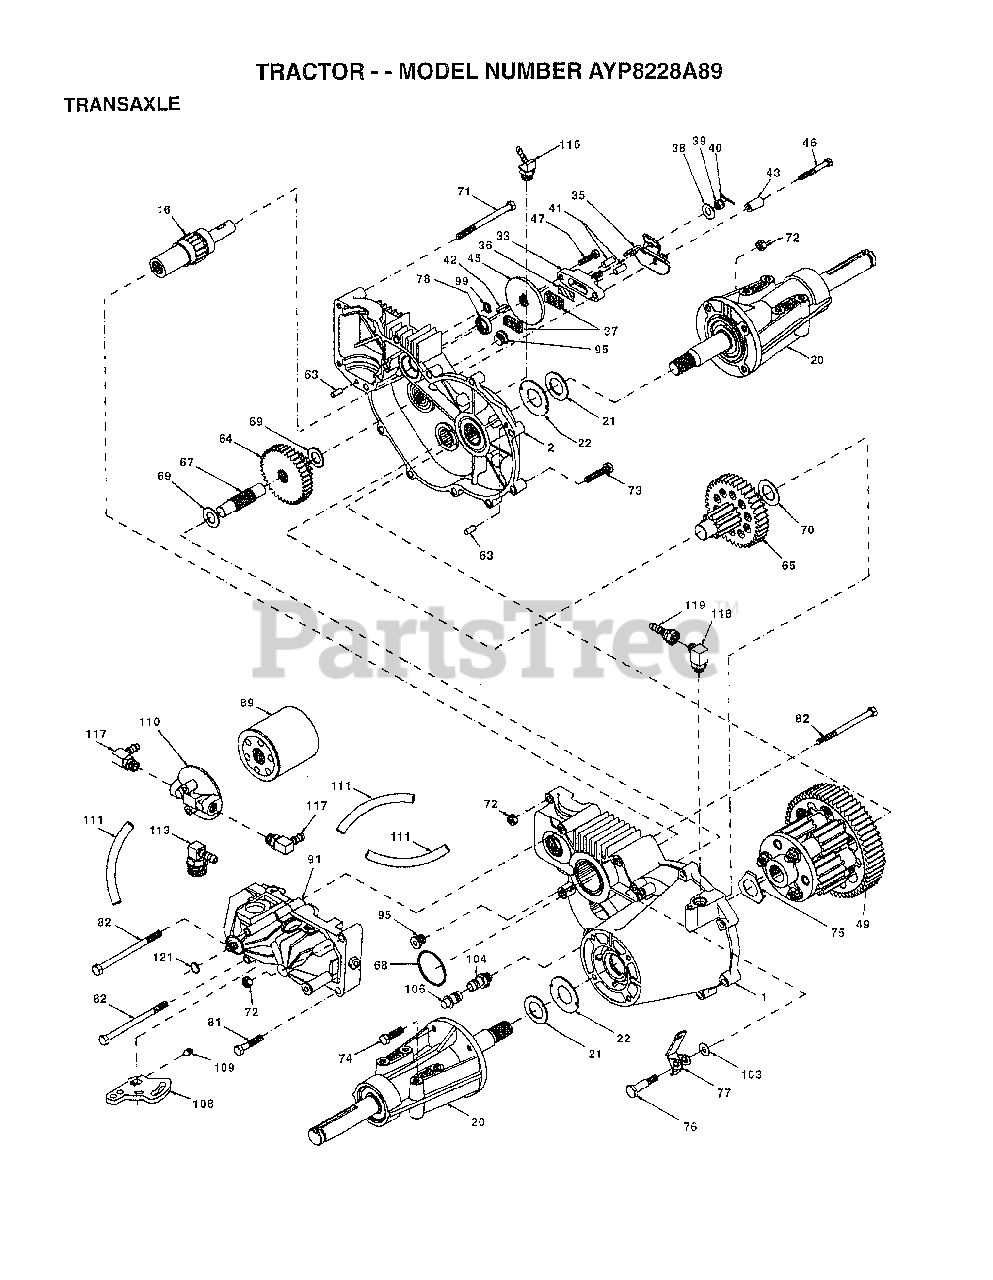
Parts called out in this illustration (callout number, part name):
1	HOUSING LH 70086
2	HOUSING RH 70088
16	SHAFT BRAKE 62877
20	AXLE MTG 70087
21	WASHER 44805
22	WASHER 44806
33	YOKE.BRAKE.62589
35	ARM BRAKE 50214
36	PUCK PLATE 44134
37	PUCK BRAKE 44132
38	WASHER HYD 44130
41	PIN BRAKE 44127
42	KEY HI PRO 44143
43	SPACER 50259
45	DISC BRAKE 44090
46	BOLT 1/4-20 44276
47	BOLT 1/4-20 44433
49	DIFFERENTIAL62834
63	PIN DOWL 44757
64	GEAR R14-38 44775
65	PINION DRIV 70051
67	SHAFT-44779
68	O RING 44781
69	WASHER 44795
70	WASHER 44794
71	BOLT 5/16 44827
72	NUT HXLK 43064
73	BOLT 5/16 44841
74	SCREW 5/16 45089
75	WASHER DIF 44880
76	BOLT SHOULD 44785
77	ARM FREEWHL 44786
78	SEAL.OIL.44761
81	BOLT 5/16 43084
82	BOLT 5/16 44820
89	FILTER SPIN 50037
95	PLUG.9005110-5600
103	WASHER.50169
104	CAP.VENT.70109
106	O-RING.ASM.70110
108	ARM.CONTROL.45007
109	SCREW.SET.50018.
110	FILTER.HEAD.50207
111	HOSE.5/16.50208.
113	FITTING.SAE.50210
116	FITTING.SAE.50213
117	FITTING.SAE.50249
118	FITTING.MAL.50251
119	FITTING.FEM.50250
121	RING.RET.2003016.
